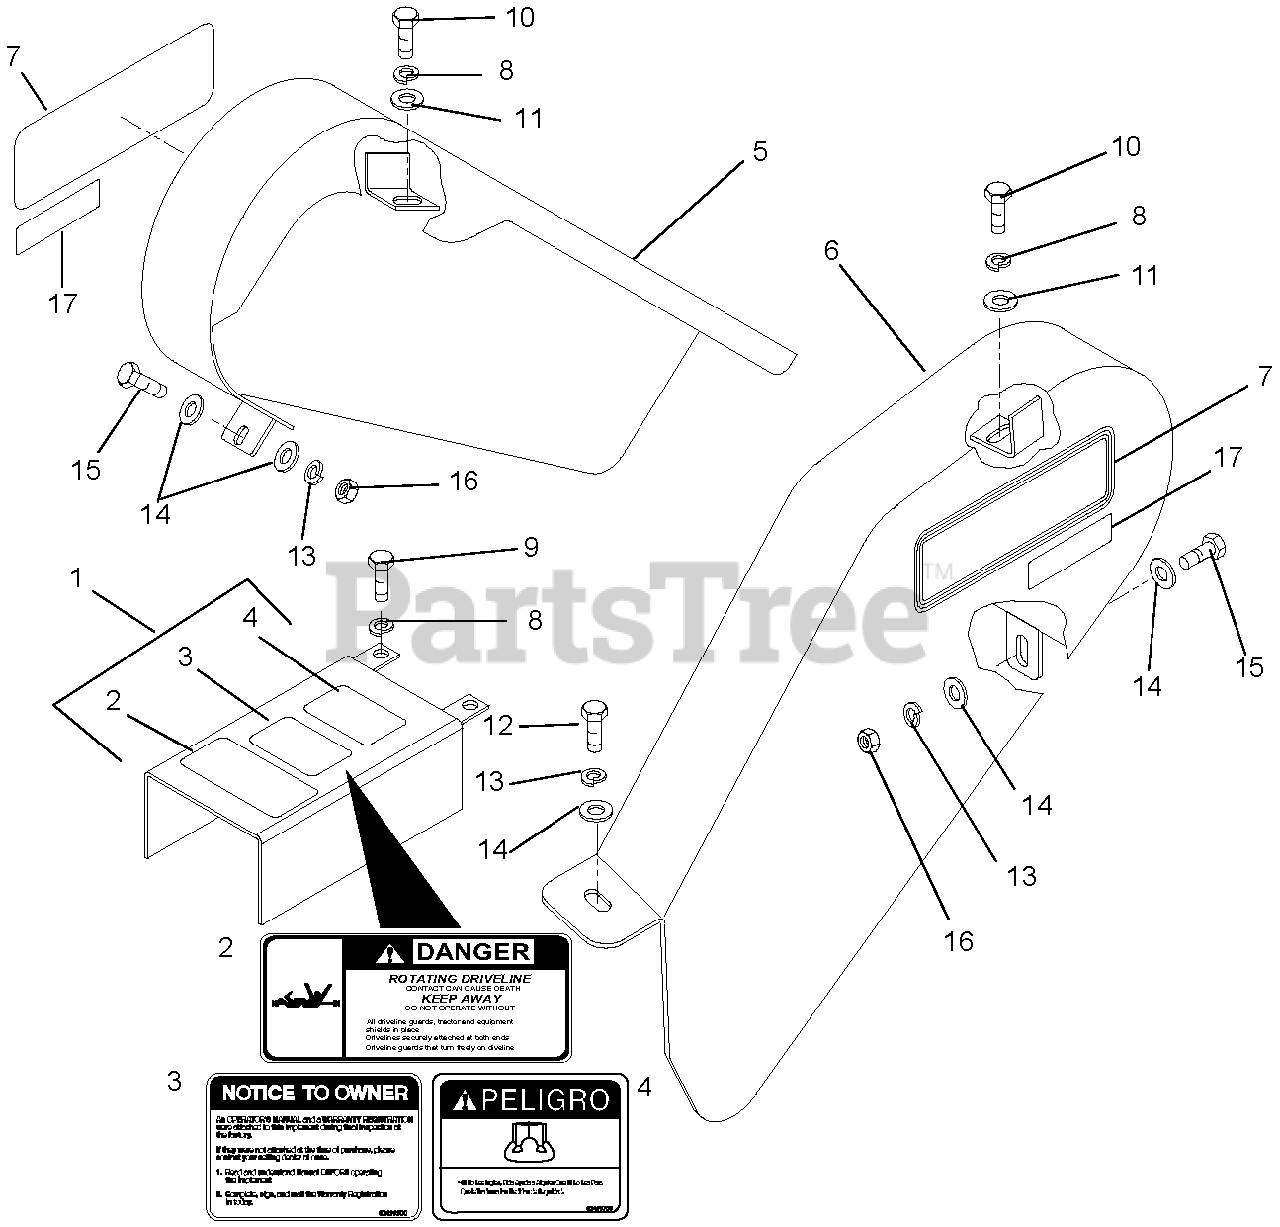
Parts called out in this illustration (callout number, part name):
1	Guard Assembly, Driveshaft
2	Decal, Danger
3	Decal, Notice to Owner
4	Decal, Danger
5	Weldment, Right Hand Drive Guard
6	Weldment, Left Hand Drive Guard
7	Decal, Model TVM-3077
8	Washer, Lock .50
9	Cap Screw, Hex Head .50-13 x .75
10	Cap Screw, Hex Head.50-13 x 1
11	Washer, Flat .50
12	Cap Screw, Hex Head .375-16 x .75
13	Washer, Lock .375
14	Washer, Flat .375
15	Cap Screw, Hex Head .375-16 x 1
16	Nut, Hex .375-16 CP
17	Decal, Gravely Turf 10" Logo
